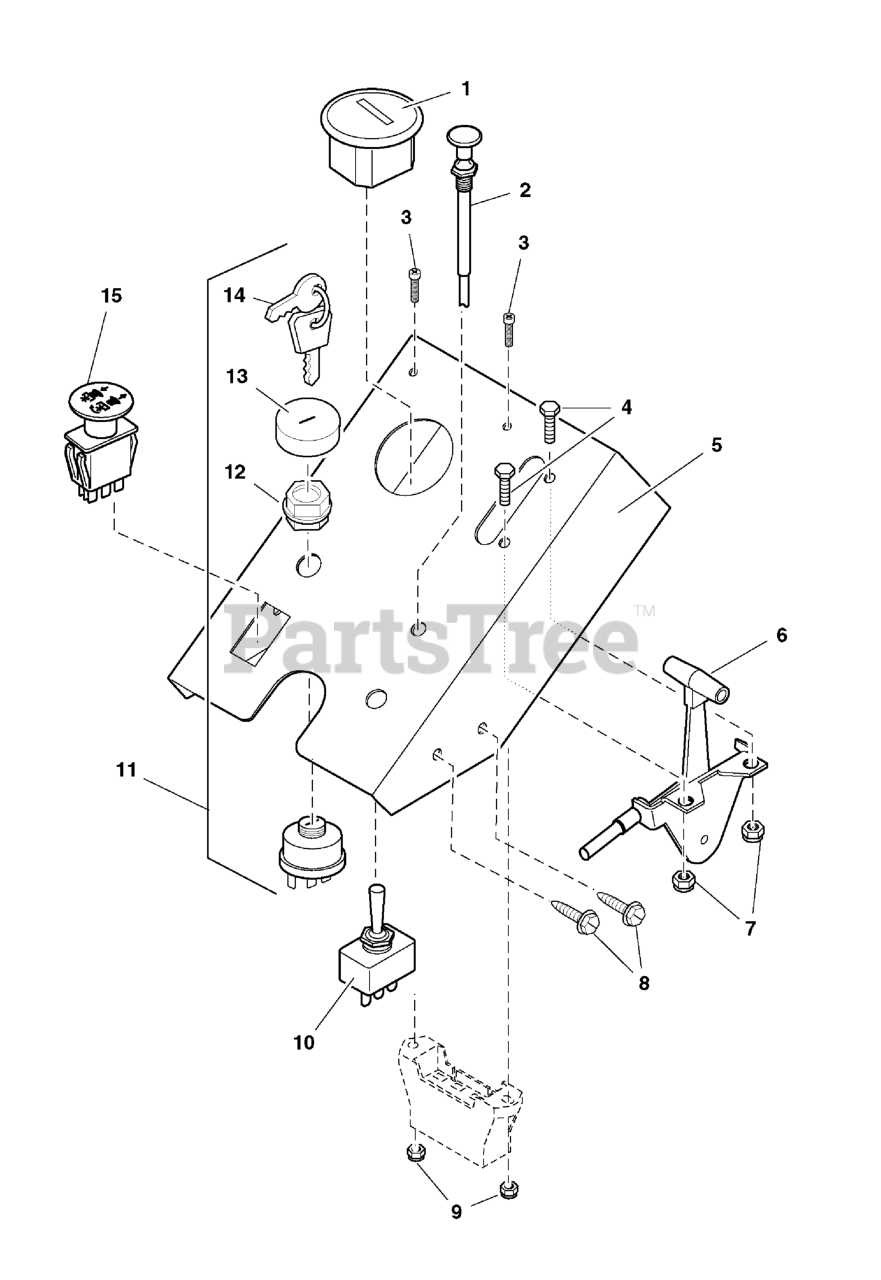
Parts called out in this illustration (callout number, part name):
1	HOUR METER
2	CABLE, CHOKE CONTROL, 45
2	CABLE, Choke Control, 57"
3	SCREW, #10-24 X 1 RS, CZ
4	BOLT, 1/4-20 x 3/4
5	DASH PANEL
6	CABLE, Throttle, 54"
7	NUT, 1/4-20 HEX NYLON LOCK
8	BOLT, Self-Tapping, 1/4-20 x 3/4
9	NUT, #10-24 Hex Nylon Lock
10	SWITCH, Actuator
11	SWITCH, IGNITION, 6 POST
12	PLASTIC NUT
13	COVER, PLASTIC, SNAP ON
14	KEY, IGNITION MOLDED SET
15	SWITCH, BLADE ENGAGEMENT
